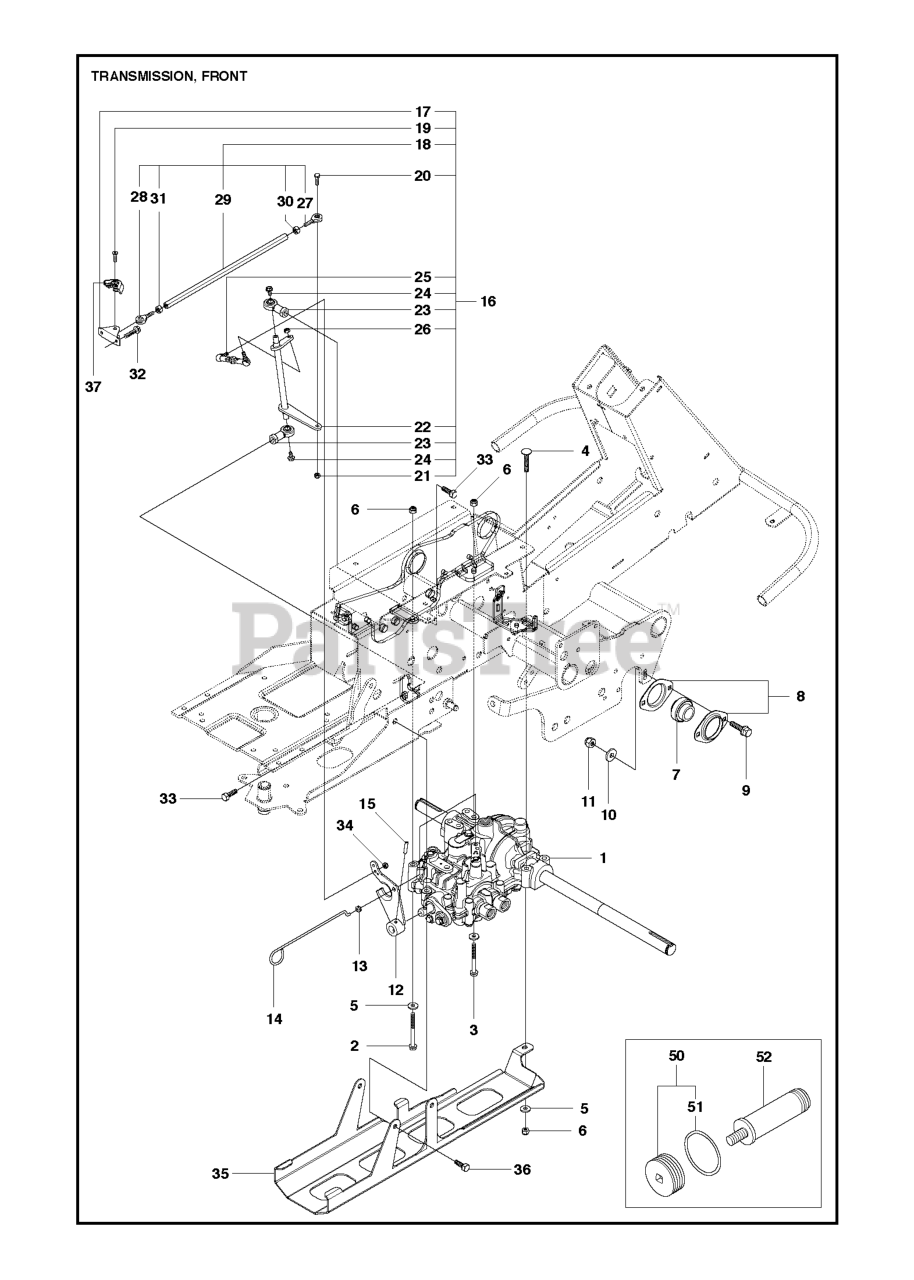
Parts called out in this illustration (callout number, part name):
5	WASHER BRB 8.4X17
6	LOCKNUT M8
8	BEARING HOUSING
9	BOLT
10	WASHER BRB 8.4X17
11	LOCKNUT M8
13	FUEL TANK BUSHING
21	NUT FLANGE - M6
24	SCREW EHHFM
25	ADJUSTING ROD
26	NUT FLANGE - M6
33	Screw M10x25
34	LOCKNUT M6
52	FILTER
